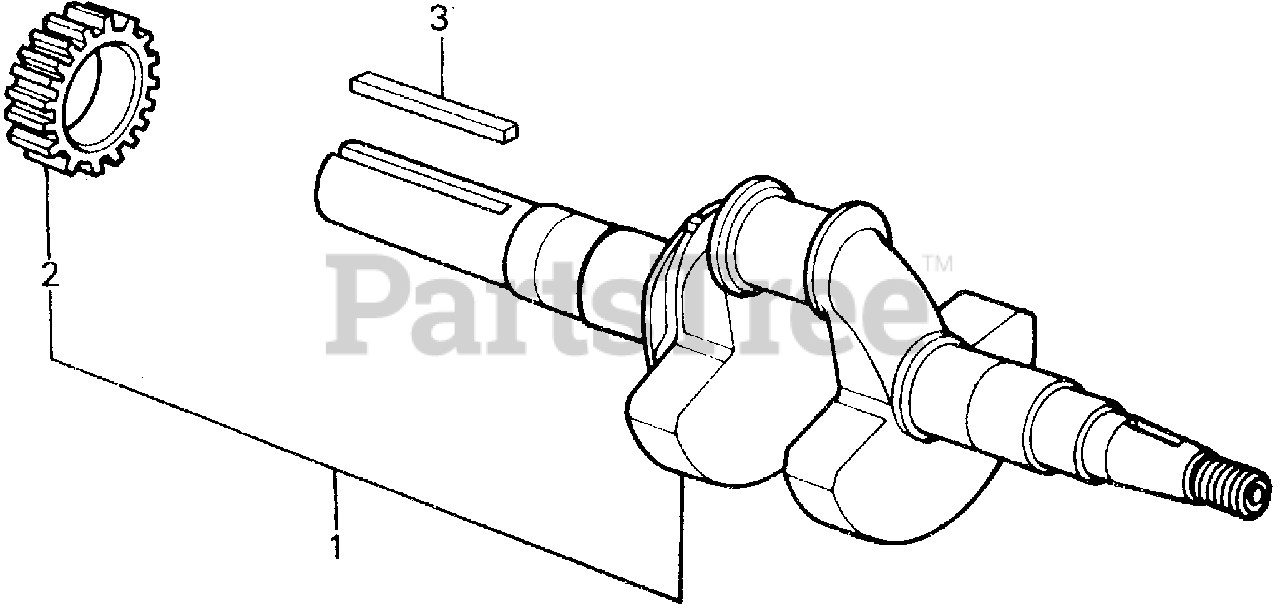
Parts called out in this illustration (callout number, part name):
1	CRANKSHAFT
2	GEAR, TIMING
3	KEY (5X5X33)
